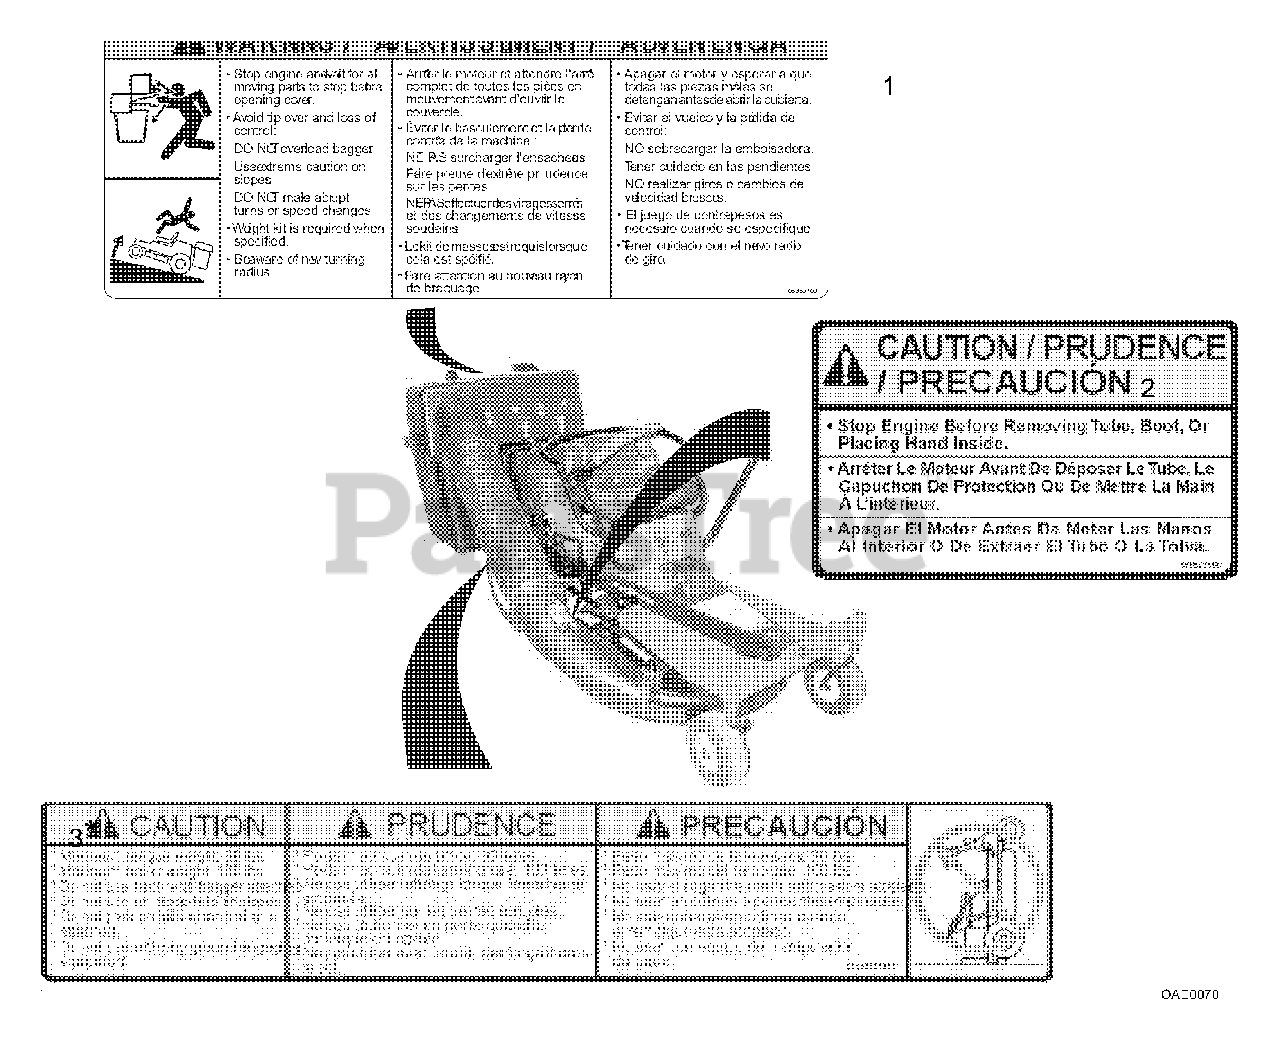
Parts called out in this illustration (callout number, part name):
1	DECAL, BAGGER COVER
2	DECAL-BOOT CAUTION
3	DECAL-HITCH 100#
